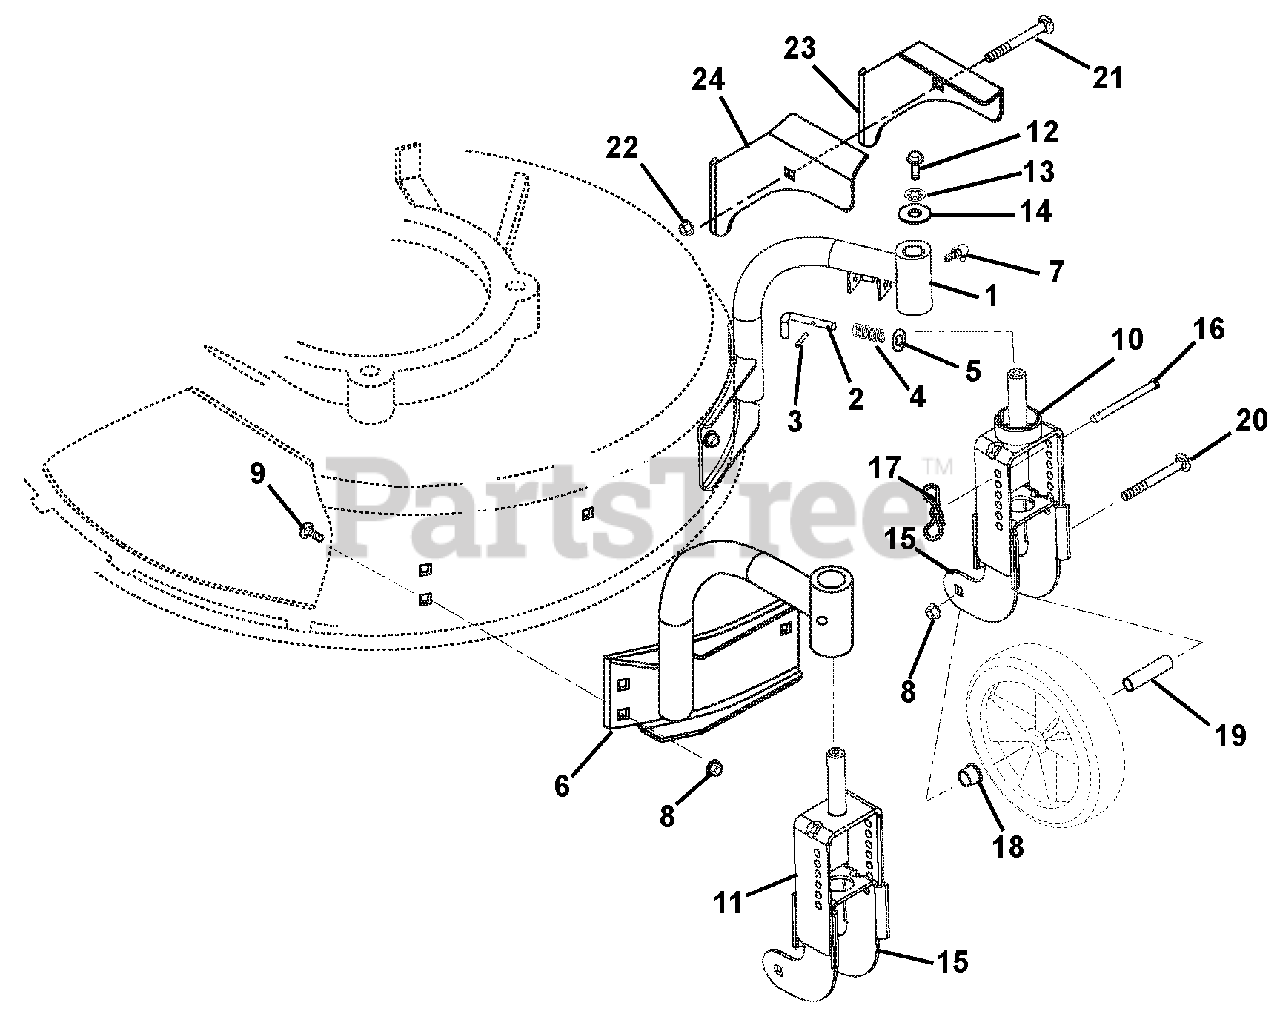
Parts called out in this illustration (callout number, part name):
1	Assembly, Mount Left Hand With Bushings
2	Pin, Lockout
3	Pin, Roll .094 x .50
4	Spring, Compression - Swivel Lockout
5	Washer, Flat Steel .281 x .62 x .065
6	Assembly, Right Hand Mount With Bushings
7	Fitting, Lube .25-28 x .256
8	Nut, Spin Lock Flange .312-18
9	Bolt, Round Head Square Neck .31-18 x .50 Grade 5
10	Yoke, Left Hand Outer
11	Yoke, Right Hand Outer
12	Bolt, Hex .25-20 x .75 Grade 5
13	Washer, Locking .25 x .062 Regular
14	Washer, Flat Steel .28 x 1.00 x .063
15	Yoke, Inner
16	Pin, Height Adjustment
17	Pin, Bow Tie Locking Cotter
18	Bushing, Flange .50 x .625 x .50 x .75
19	Spacer, Wheel
20	Bolt, Round Head Square Neck .31-18 x 2.75
21	Bolt, Round Head Square Neck .25-20 x 1.50 Grade 5
22	Nut, Locking Flange .25-20
23	Bracket, Hood Cable Left Hand
24	Bracket, Hood Cable Right Hand
